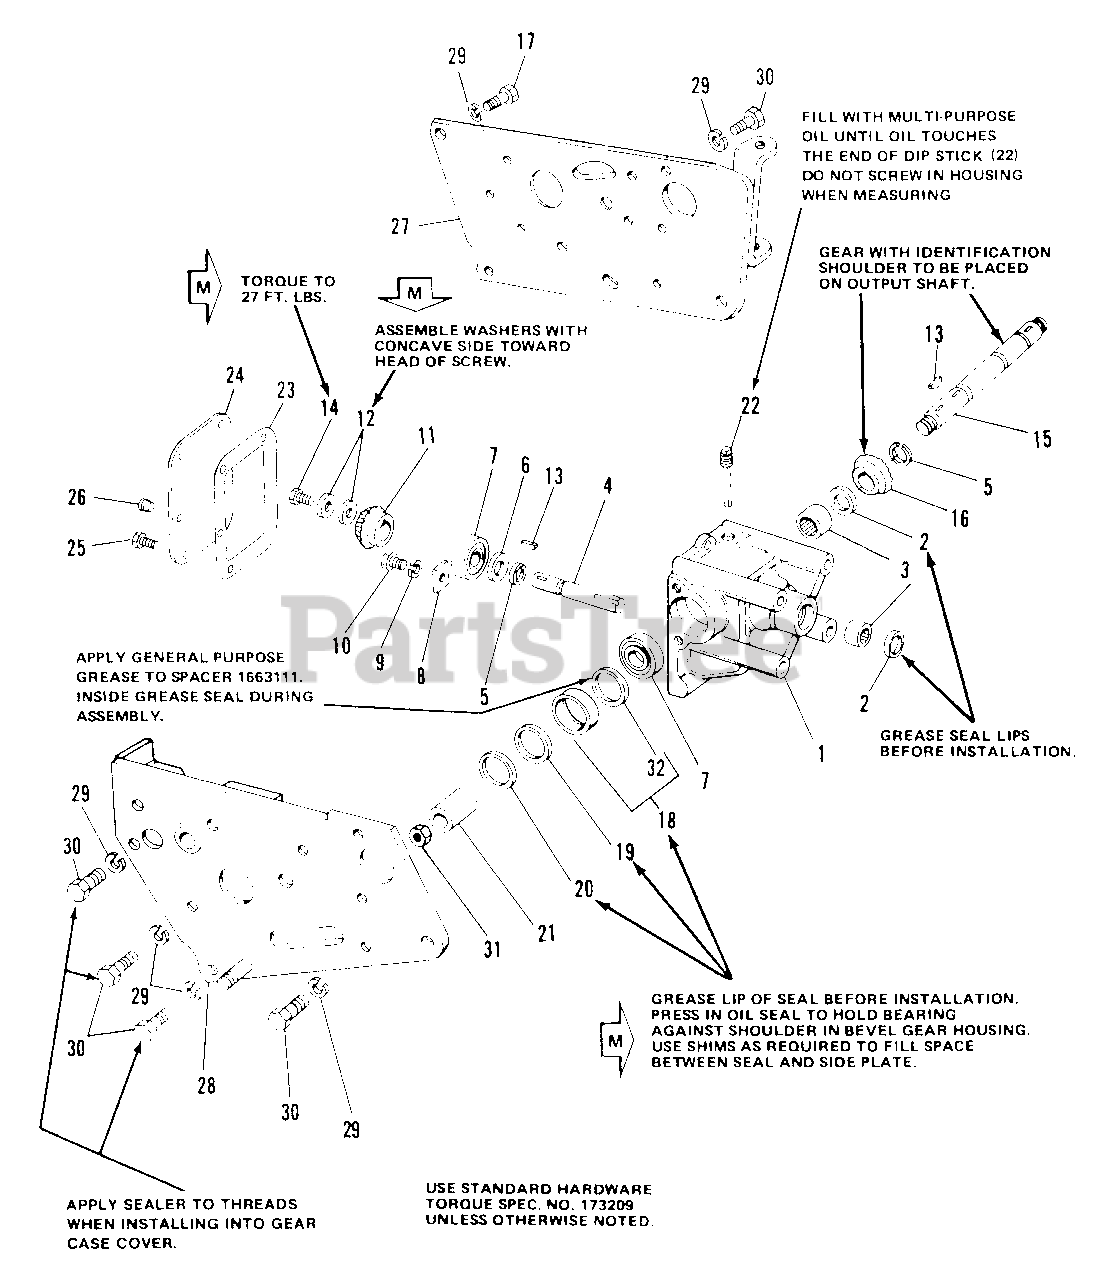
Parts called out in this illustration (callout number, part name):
1	HOUSING, Bevel Gear
3	BEARING, Needle
4	SHAFT, Driver
5	RING, Retaining
7	BEARING, Ball
8	PLATE, Bearing Clamp
9	LOCKWASHER, 5/16
10	CAPSCREW, Hex Hd., 5/16-18 x 5/8
11	GEAR, Bevel Driver
13	KEY, Woodruff, No. 9
14	CAPSCREW, Hex Hd., 5/16-18 x 3/4
15	SHAFT, Driven
16	GEAR, Bevel Driven
17	CAPSCREW, Hex Hd., 7/16-14 x 1-1/4
18	SEAL, Oil, Kit, (Replaces 171787)
25	CAPSCREW, Hex, 1/4-20 x 5/8
27	PLATE ASSY, Side, L.H.
28	PLATE ASSY, Side, R.H.
29	LOCKWASHER, 7/16
30	CAPSCREW, Hex Hd., 7/16-14 x 1
31	LOCKNUT, Hex, Jam, 3/4-16
32	SPACER, Oil Seal
